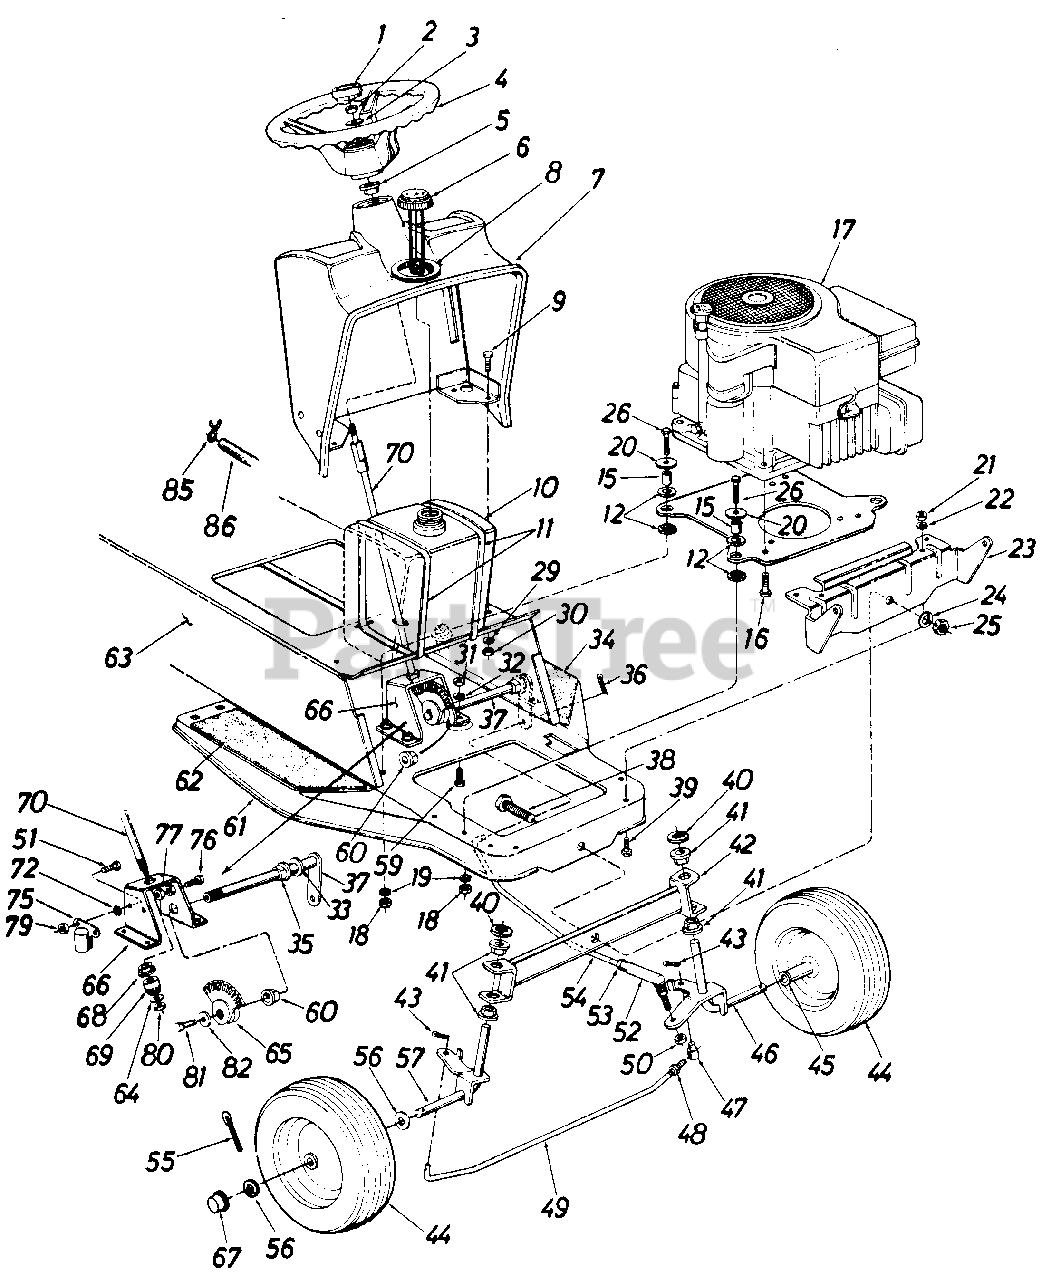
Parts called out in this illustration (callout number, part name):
1	Steering Wheel Cap
2	Hex Cent. L-Nut 5/16-18 Thd.
3	Bell-Wash. .345 I.D. x .88 O.D.
4	Steering Wheel
5	Hex Flange Bushing .63" I.D.
6	Fuel Gauge-Cap
7	Dash Panel Ass'y. w/LiRhts
8	Rubber Grommet
9	Hex Sems Scr. 1/4-20 x .75 Lg.
10	Fuel Tank
11	Cable Tie
12	Engine Mounting Grommet
15	Spacer
16	Hex Wash. Hd. Selt-Tap Screw 3/8-16 x 1.25 Lg.
17	Engine
18	Hex Nut 5/16-24 Thd.
19	L-Wash. 5/16" Scr.
20	Fl-Wash. .34" I.D. x 1.12" O.D. x .125
21	Hex Nut 5/16-18 Thd.
22	L-Wash. 5/16" Scr.
23	Front Pivot Bracket
24	L-Wash. 5/8" Scr.
25	Hex Cent. L-Nut 5/8-18 Thd.
26	Hex Scr. 5/16-24 x 1.25 H.T.
29	L-Wash. 1/4" Scr.
30	Hex Nut 1/4-20 Thd.
31	Hex Nut 5/16-18 Thd.
32	L-Wash. 5/16 Scr.
33	Fl-Wash. .812 I.D. x 1.38 O.D. x .100
34	Foot Pad-L.H.
35	Flange Brg. w/Flats
36	Cotter Pin 3/32" Dia. x 75" Lg.*
37	Steering Arm Ass'y.
38	Hex Scr. 5/8-18 x 1.62" Lg.
39	Hex Sems Scr. 5/16-18 x .75 Lg.
40	Push Nut
41	Hex Flange Bushing .62
42	Pivot Bar Ass'y.
43	Cotter Pin 1/8n Dia. x .75" Lg.
44	Front Wheel Ass'y.
45	Flange Bearing
46	Front Axle Ass'y.-L.H.
47	Pivot Bushing
48	Hex Jam Nut 3/8-24 Thd.
49	Tie Rod
50	Hex Ins. L-Nut 3/8-24 Thd.
51	Hex Scr. 1/4-20 x .50" Lg.
52	Ball Joint Ass'y.
53	Hex Jam Nut 3/8-24 Thd.
54	Drag Link
55	Cotter Pin 1/8" Dia. x 1.25" Lg.
56	Fl-Wash. .630 I.D. x 1.120 O.D. x .100
57	Front Axle Ass'y.-R.H.
59	Hex Sems Scr. 5/16-18 x .75" Lg.
60	Flange Brg. w/Flats
61	Front Frame Ass'y.
62	Foot Pad-R.H.
63	Rear Frame
64	Fl-Wash. 5/16n Scr.
65	Side Gear
66	Steering Gear Support Ass'y.
67	Hub Cap
68	Hex Flange Bushing .50 I.D.
69	Pinion Gear
70	Steering Shaft
72	Ext. L-Wash. 1/4" Scr.
75	Solenoid
76	Hex Scr. Nylon 3/8-16 x 1.25" Lg.
77	Hex Cent. L-Nut 3/8-16 Thd.
79	Hex Nut 1/4-20 Thd.
80	Hex Cent. L-Nut 5/16-24 Thd.
81	Hex Scr. 3/8-24 x .75" Lg.
82	Bell-Wash.
85	Hose Clamps
86	Fuel Line 13" Lg.
